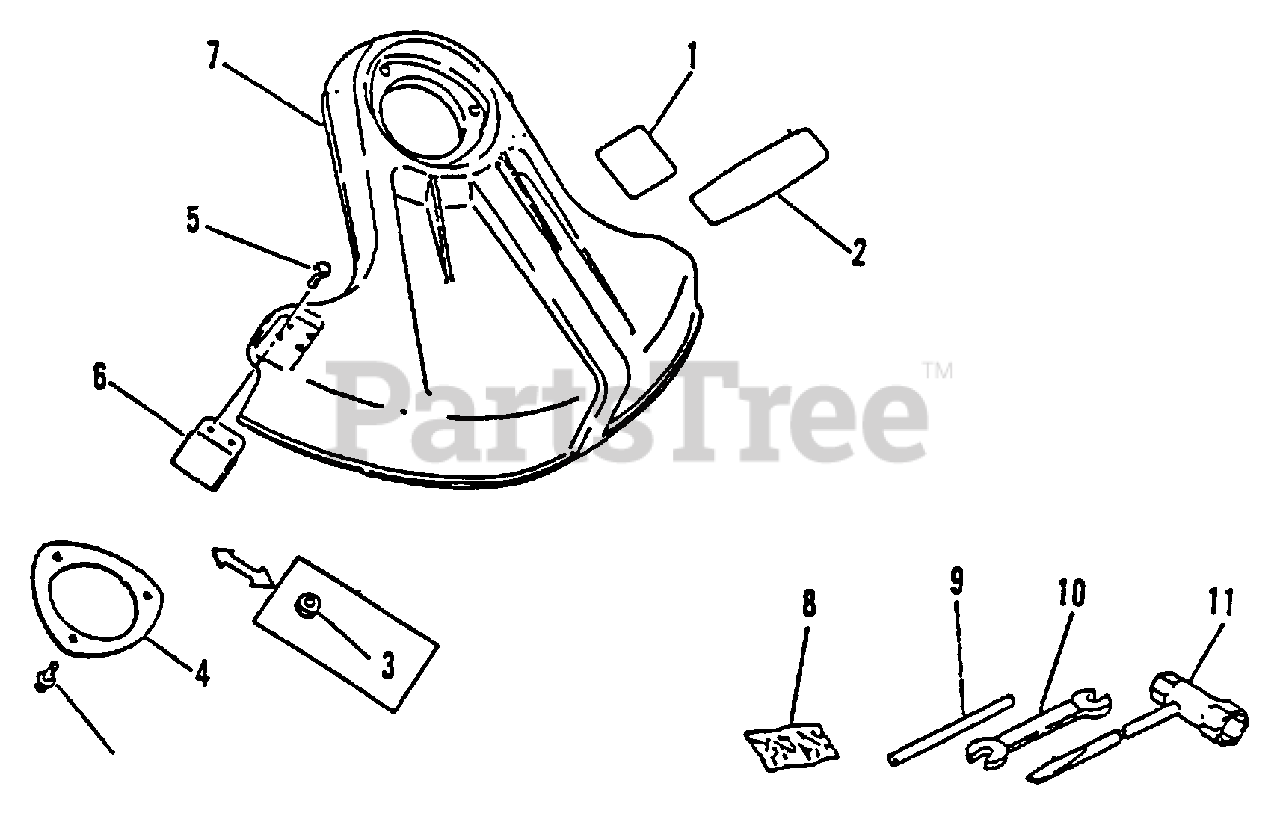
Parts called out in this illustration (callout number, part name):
1	LABEL, CAUTION
2	LABEL, ECHO
3	NUT M5
4	PLATE, SHIELD Ø49.5 MM
5	SCREW 5×16
6	KNIFE, TRIMMER LINE
7	DEBRIS SHIELD ASSY
8	PIN, COTTER 2×22 (PKG. OF 10)
9	TOOL, LOCKING 5×120 MM
10	SPANNER 8×10
11	T-WRENCH 17x-19 L200
